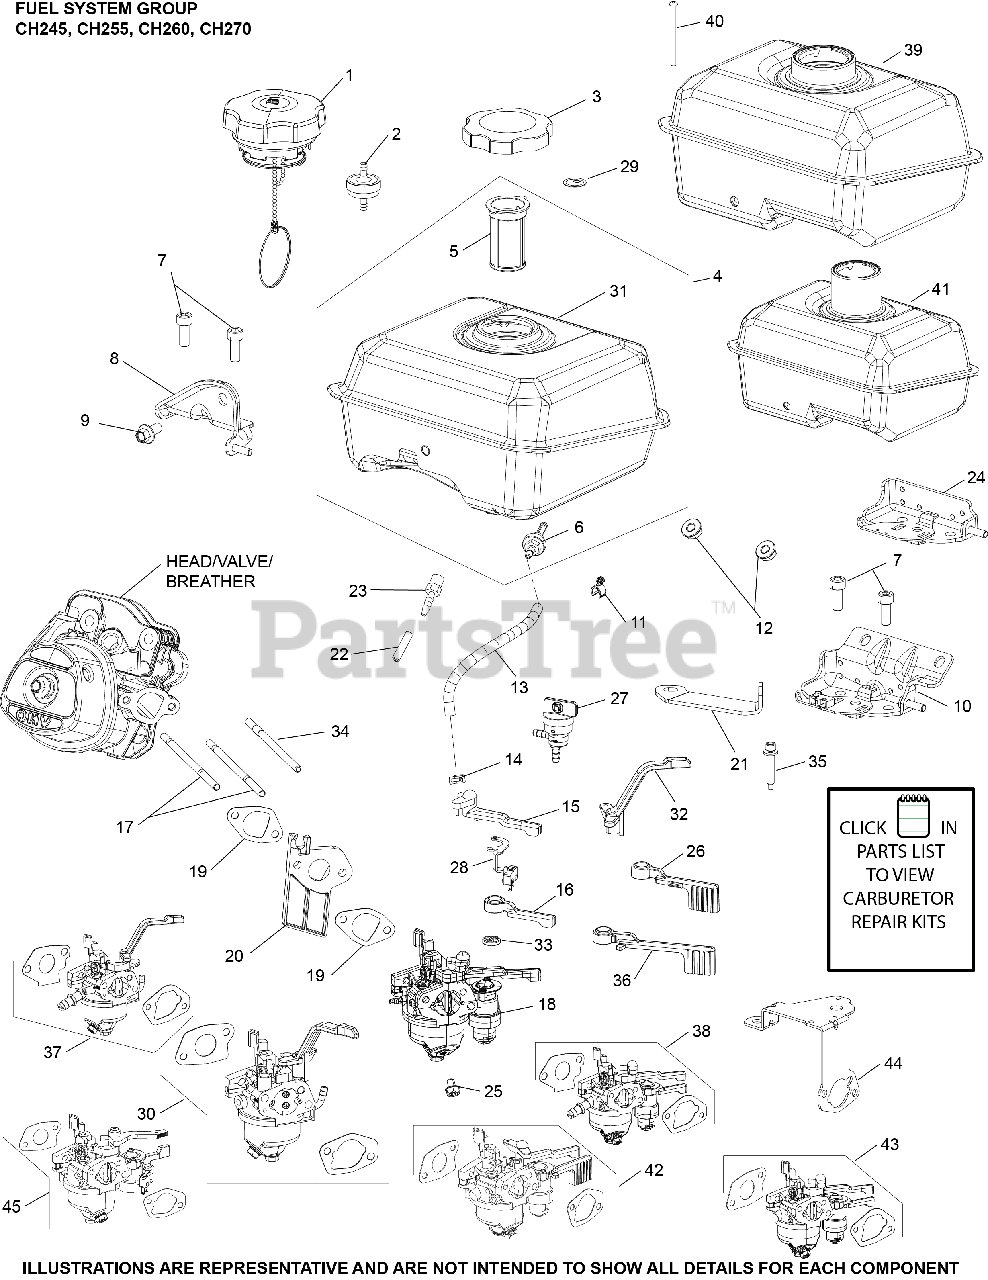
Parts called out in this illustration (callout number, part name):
3	CAP, FUEL TANK
4	KIT, FUEL TANK ASSEMBLY
5	FILTER, FUEL TANK
6	FITTING, FUEL ASSY
11	CLIP, FUEL HOSE
13	LINE, FUEL (10"-CUT TO LENGTH)
14	CLAMP, FUEL LINE
17	STUD, CARBURETOR
18	KIT, CARBURETOR ASSEMBLY
19	KIT, INTAKE GASKET
20	INSULATOR, CARBURETOR
29	KIT, FUEL SCREEN
33	SEAL, INLET VALVE
NI	KIT, HIGH ALTITUDE (4,000-8,000 FT)
NI	KIT, HIGH ALTITUDE - USE 14 755 04-S
NI	KIT, CARBURETOR REPAIR
